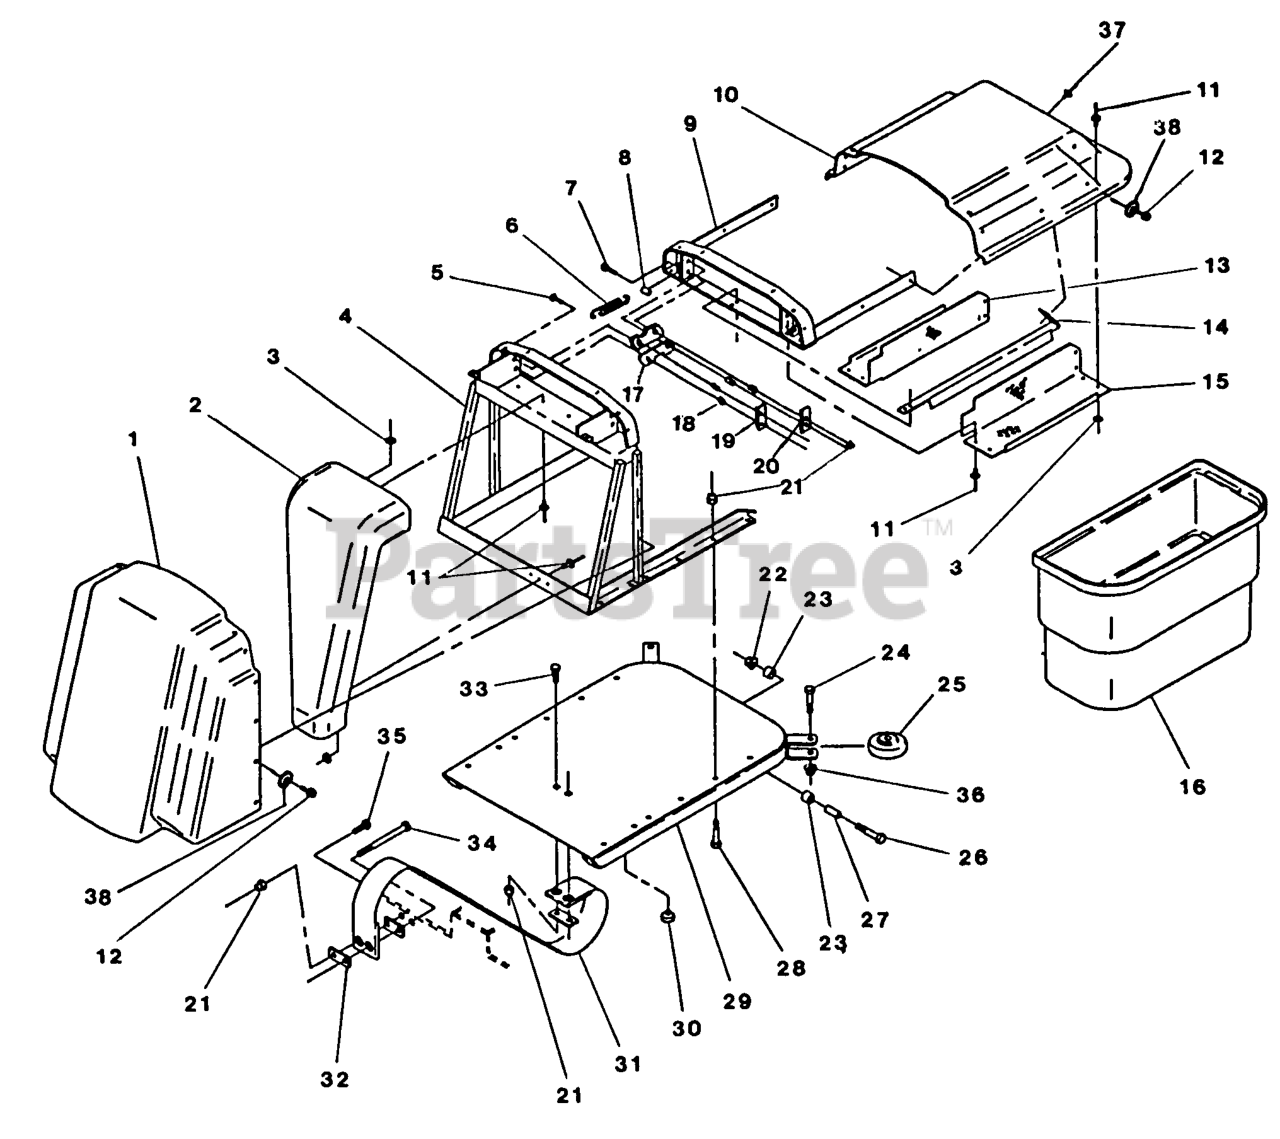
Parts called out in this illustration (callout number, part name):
6	SPRING,CATCHER LID
8	BUSHING,LID SPRING
10	TOP,GRASS CATCHER
13	SCREEN,PERFORATED RH PNT
15	SCREEN,PERFORATED LH PNT
17	LINK,HINGE PLTD
23	SLEEVE-BEARING
25	WHEEL,RUBBER
27	BUSHING,BOX PIVOT
31	STRAP,BOX RESTRAINT
32	CLAMP,STRAP
33	Bolt, Carriage 1/4-20 X 1
37	Pop Rivet, Steel 3/16 X .250
